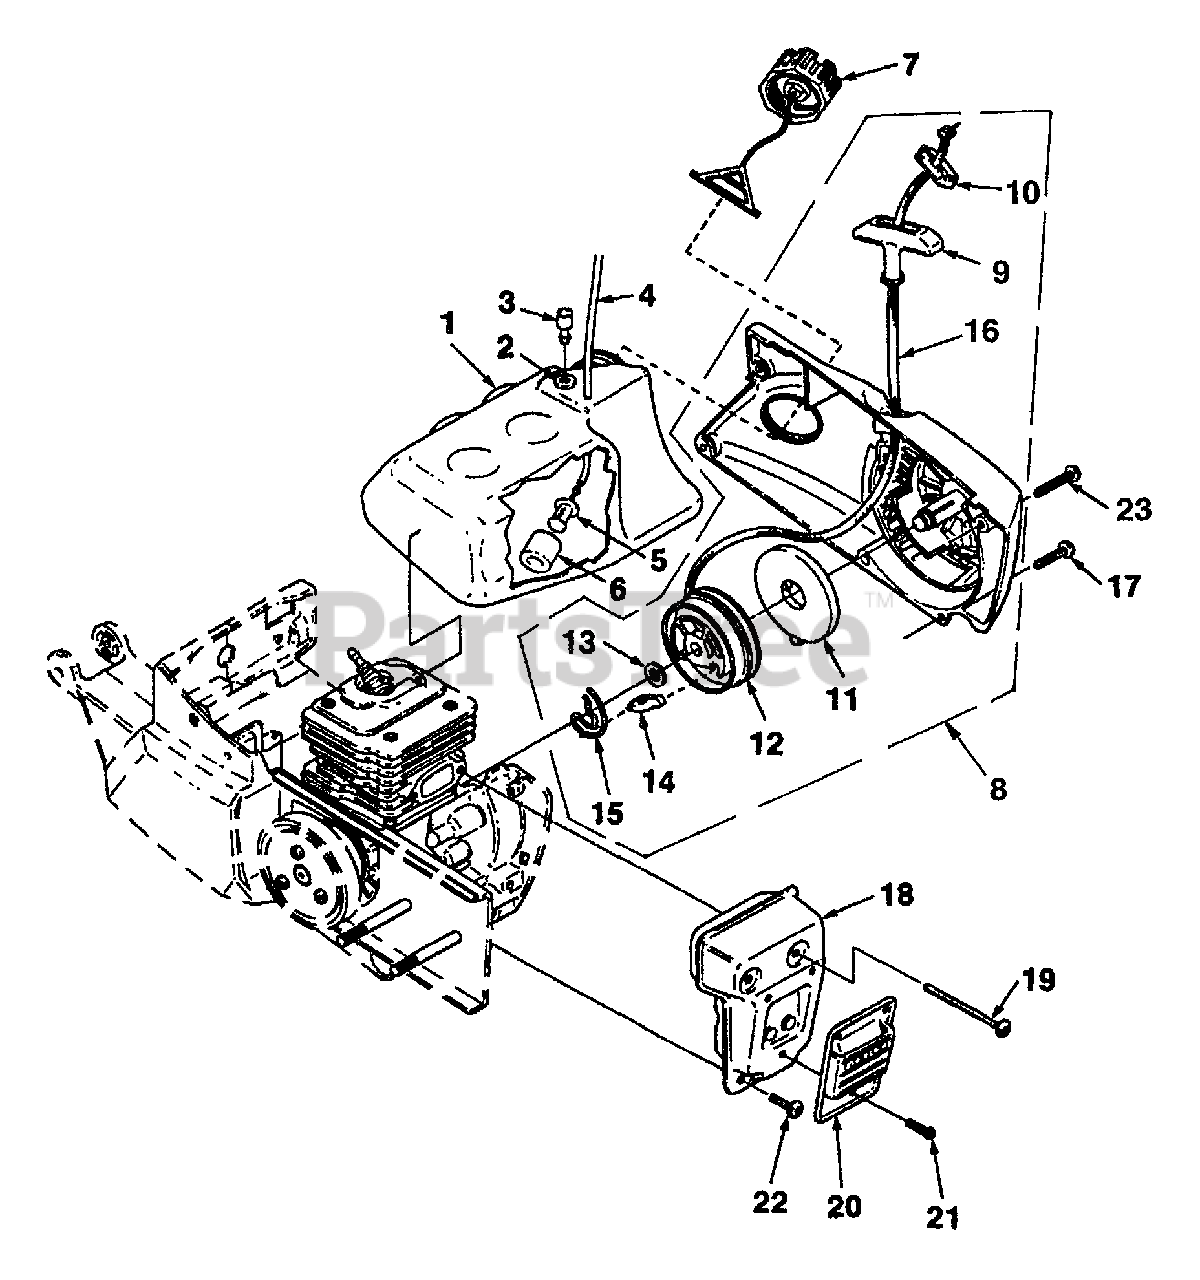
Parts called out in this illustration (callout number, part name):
1	TANK-Fuel
2	GROMMET
3	FILTER SLEEVE (Complete)
4	TUBING-Rubber (10")
5	FILTER-Fuel
6	FILTER-Fuel
7	CAP-Tank (w/Retainer)
8	STARTER (Complete)
9	GRIP-Starter (w/insert)
10	INSERT-Rope Ret.
11	SPRING & CONTAINER
12	PULLEY ASSEMBLY
13	WASHER-Thrust
14	PAWL-Starter
15	CLIP-Retainer
16	ROPE- Starter (45")
17	SCREW-Truss Hd. (10-24 X 3/4")
18	MUFFLER
19	SCREW-Truss Hd. (10-24 X 2 1/2")
20	CAP-Muffler
21	SCREW-Machine Hex Hd. (8-32 X 1/2"
22	SCREW-Torx (10-24 X 1/2")
23	SCREW-Truss Hd. (10-24 X 3 1/4")
